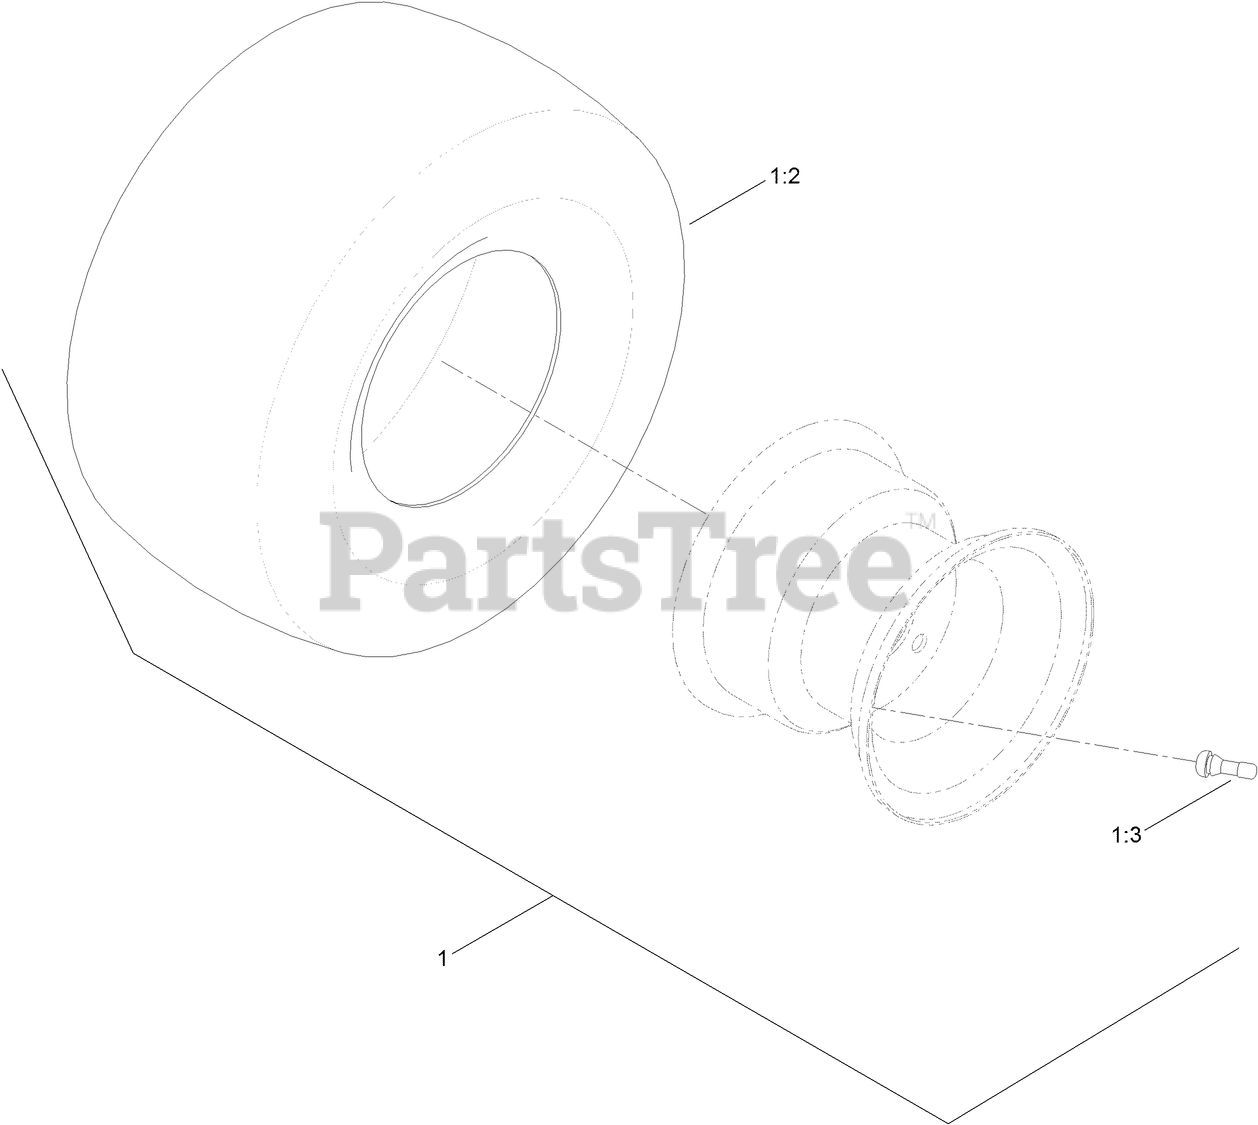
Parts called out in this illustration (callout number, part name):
1	2 PLY TIRE AND WHEEL ASM
1:2	TIRE-2 PLY
1:3	STEM-VALVE
